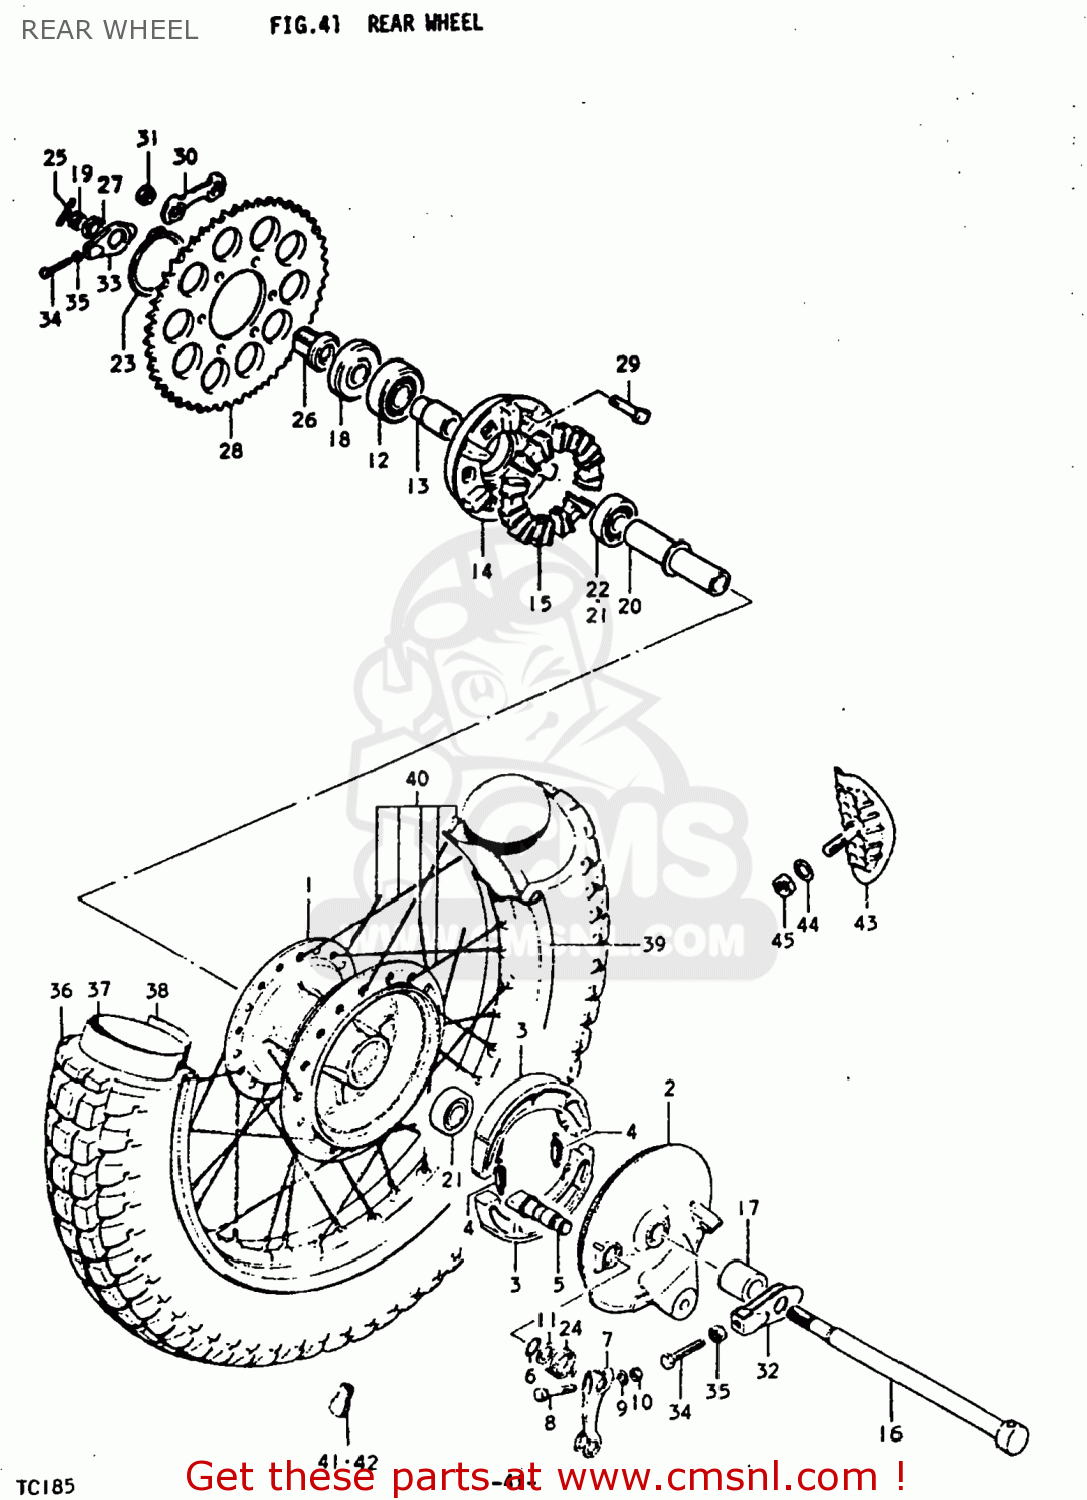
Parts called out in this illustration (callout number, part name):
1	HUB,REAR
2	PANEL,REAR HUB
3	SHOE,BRAKE
4	SPRING(L:34)
5	CAM,FR BRAKE
6	O RING(D:2.5,ID:11.4)
7	LEVER,REAR BRAKE CAM
8	BOLT
9	WASHER
10	NUT
11	WASHER(12.5X20X1)
12	BEARING
13	SPACER,REAR HUB BEARING
14	DRUM,REAR SPROCKET MOUNT
15	ABSORBER,RR WHEEL HUB SHOCK
16	AXLE,REAR
17	SPACER
18	SPACER,RR AXLE,L
19	NUT 12MM
20	SPACER
21	BEARING
22	BEARING
23	CIRCLIP
24	SPRING
25	COTTER PIN
26	SPACER,CHAIN ADJUSTER,L
27	NUT
28	SPROCKET,REAR
29	BOLT(8X32)
30	WASHER
31	NUT
32	ADJUSTER,CHAIN
33	ADJUSTER,CHAIN
34	BOLT
35	NUT
36	TIRE 3.50-18 089-458MM
37	TUBE ASSEMBLY,WHEEL,INNER
38	PROTECTOR,INNER TUBE
39	RIM,REAR WHEEL
40	SPOKE SET,REAR
41	BALANCER,WHEEL (B)
42	BALANCER,WHEEL (30G)
43	STOPPER,BEAD
44	WASHER
45	NUT
